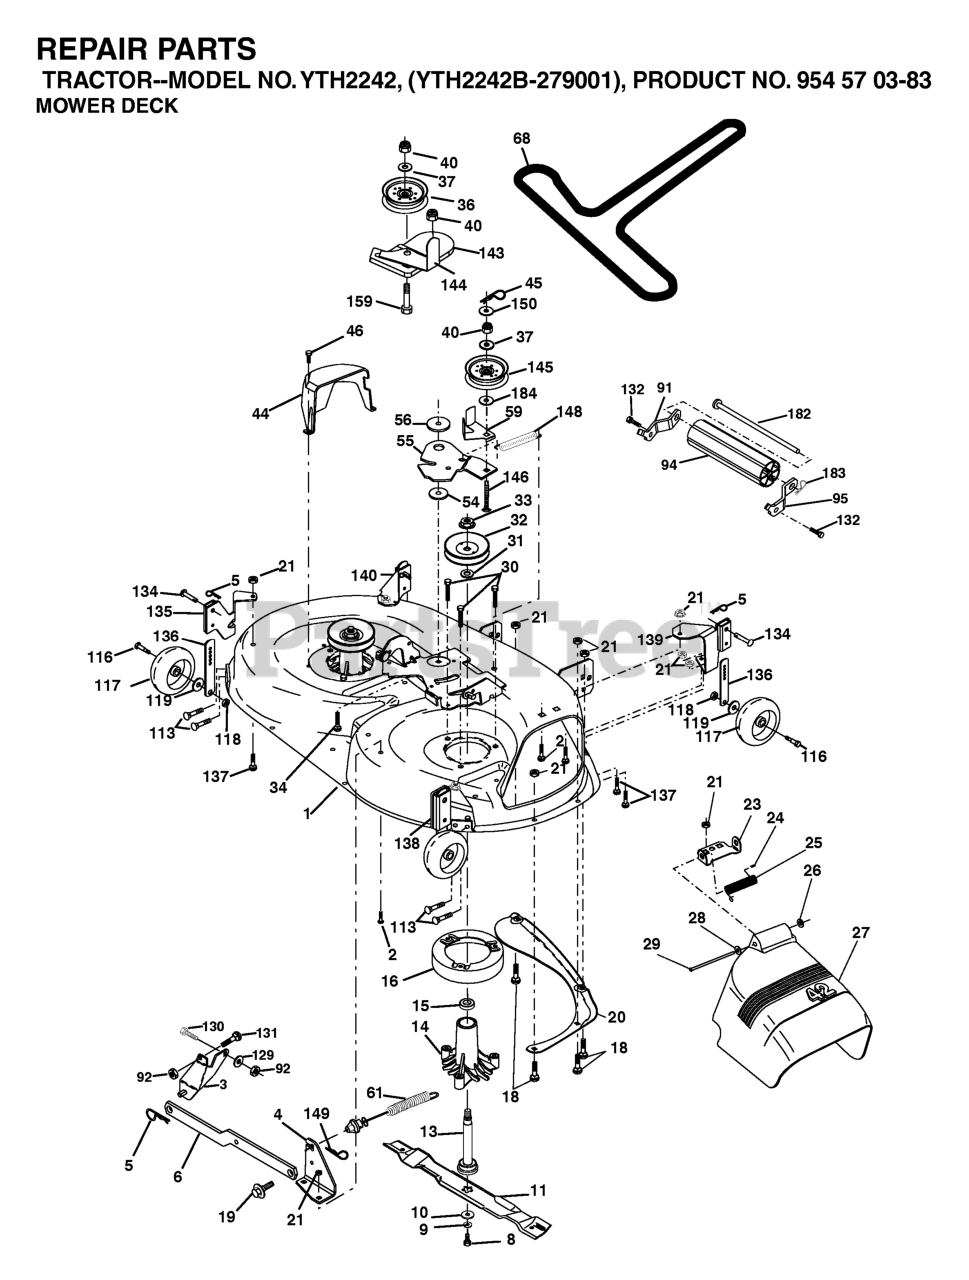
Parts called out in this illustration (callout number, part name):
1	MOWER DECK SHELL 42"
2	RP BOLT 5/16-18 X3/4 ZN/YEL GR
3	BRKT ASM SWAY BAR
4	BRACKET SWAY BAR 42" DECK
5	RETAINER-SPRNG RB
6	BAR SWAY DECK
8	BLADE BOLT
9	LOCKWASHER
10	WASHER.BLADE
11	BLADE.42".MULCH
13	SHAFT ASM VENT
14	HOUSING.MANDREL.VENTED (MACHD)
16	STRIPPER.MANDREL.ROUND.BLACK
18	BOLT
19	BOLT SHD 5/16-18
20	BAFFLE.VORTEX
21	LOCKNUT
23	BRKT, DEFL. MOWER
24	CAP-SLEEVE LT
25	SPRING TORSION
26	NUT PUSH M
27	SHIELD DEFLECTOR
28	Washer 11/32 x 5/8 x 16 Ga SD
29	ROD.HINGE
30	SCREW, WASHER HEAD
31	WASHER
32	PULLEY MANDREL
33	NUT, FLG TOPLOCK 9/16"
36	PULLEY.IDLER.FLAT
37	WASHER
44	GUARD MANDREL LH BLACK
45	RETAINER M
46	SCREW.1/4-20X5/8
55	ARM IDLER 42" MOWER LT/YT
56	SPACER RETAINER
59	GUARD TUV IDLER
61	SPRING EXT ELEC CLUTCH
68	V-BELT PRIMARY 42"
91	BRACKET ASM NOSEROLLER LH
92	NUT
94	NOSE ROLLER
95	BRACKET ASM NOSEROLLER RH
113	SCREW 5/16"
116	SHOULDER BOLT
117	WHEEL GAGE DONUT
118	LOCKNUT
119	WASHER.5/16.FLAT.STE.STD.
129	WASHER
131	BOLT D
132	SCREW, 3/8-16X3/4
134	RIVET.PIN.HEAD.YELLOW.
135	BRACKET ASM, WHEEL
136	BAR.ADJUST.WHEEL.ANTI.SCALP.BL
137	BOLT.CARR.5/16-18X5/8.SHORT
138	BRACKET.ASM.WHL.GA.R.RH.42".GR
139	BRACKET ASM, WHEEL
140	BRACKET ASM, WHEEL
143	BRACKET, ARM IDLER
144	KEEPER BELT 42" CLUTCH
145	PULLEY.IDLER.FLAT.PLATED
146	BOLT CARRIAGE IDLER
148	IDLER RETURN SPRING
149	SPRING.RETAINER.YELLOW.ZINC
182	ROD ROLLER NOSE STANDARD
183	SPRING RETAINER
184	WASHER
